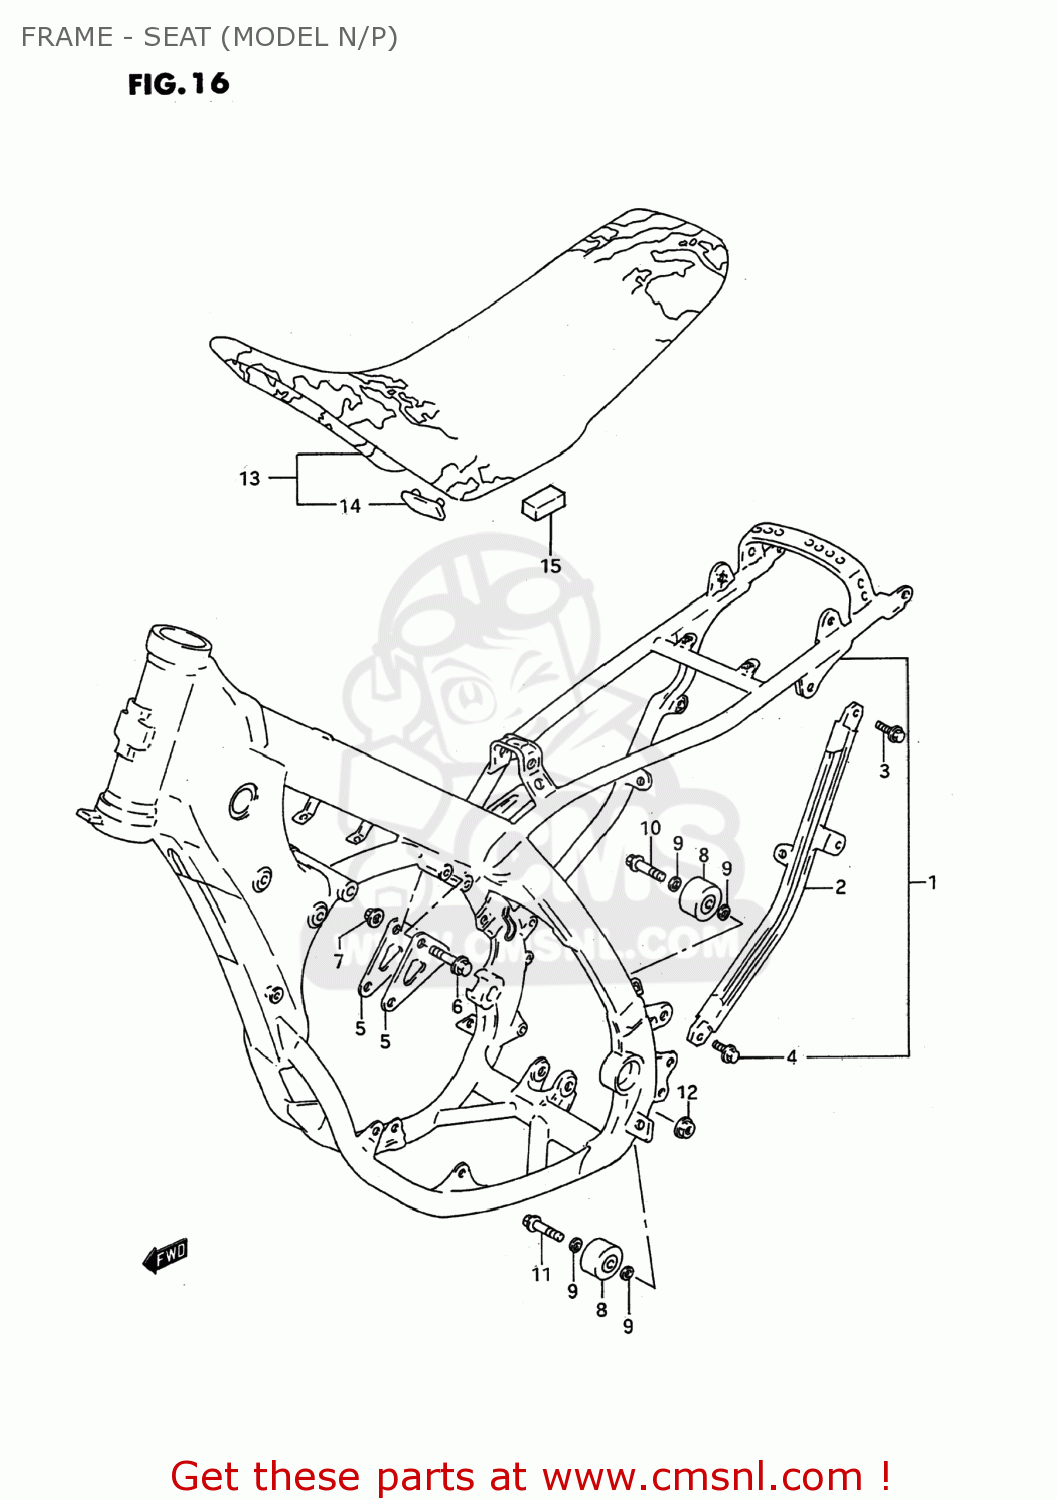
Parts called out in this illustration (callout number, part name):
1	FRAME
2	TUBE,FRAME SIDE,L
3	BOLT,LOWER
4	BOLT
5	PLATE,ENGINE MOUNTING
6	BOLT(8X41)
7	NUT
8	ROLLER,CHAIN
9	WASHER
10	BOLT(8X41)
11	BOLT(8X45)
12	NUT
13	SEAT SET
14	CUSHION
15	CUSHION,SEAT
